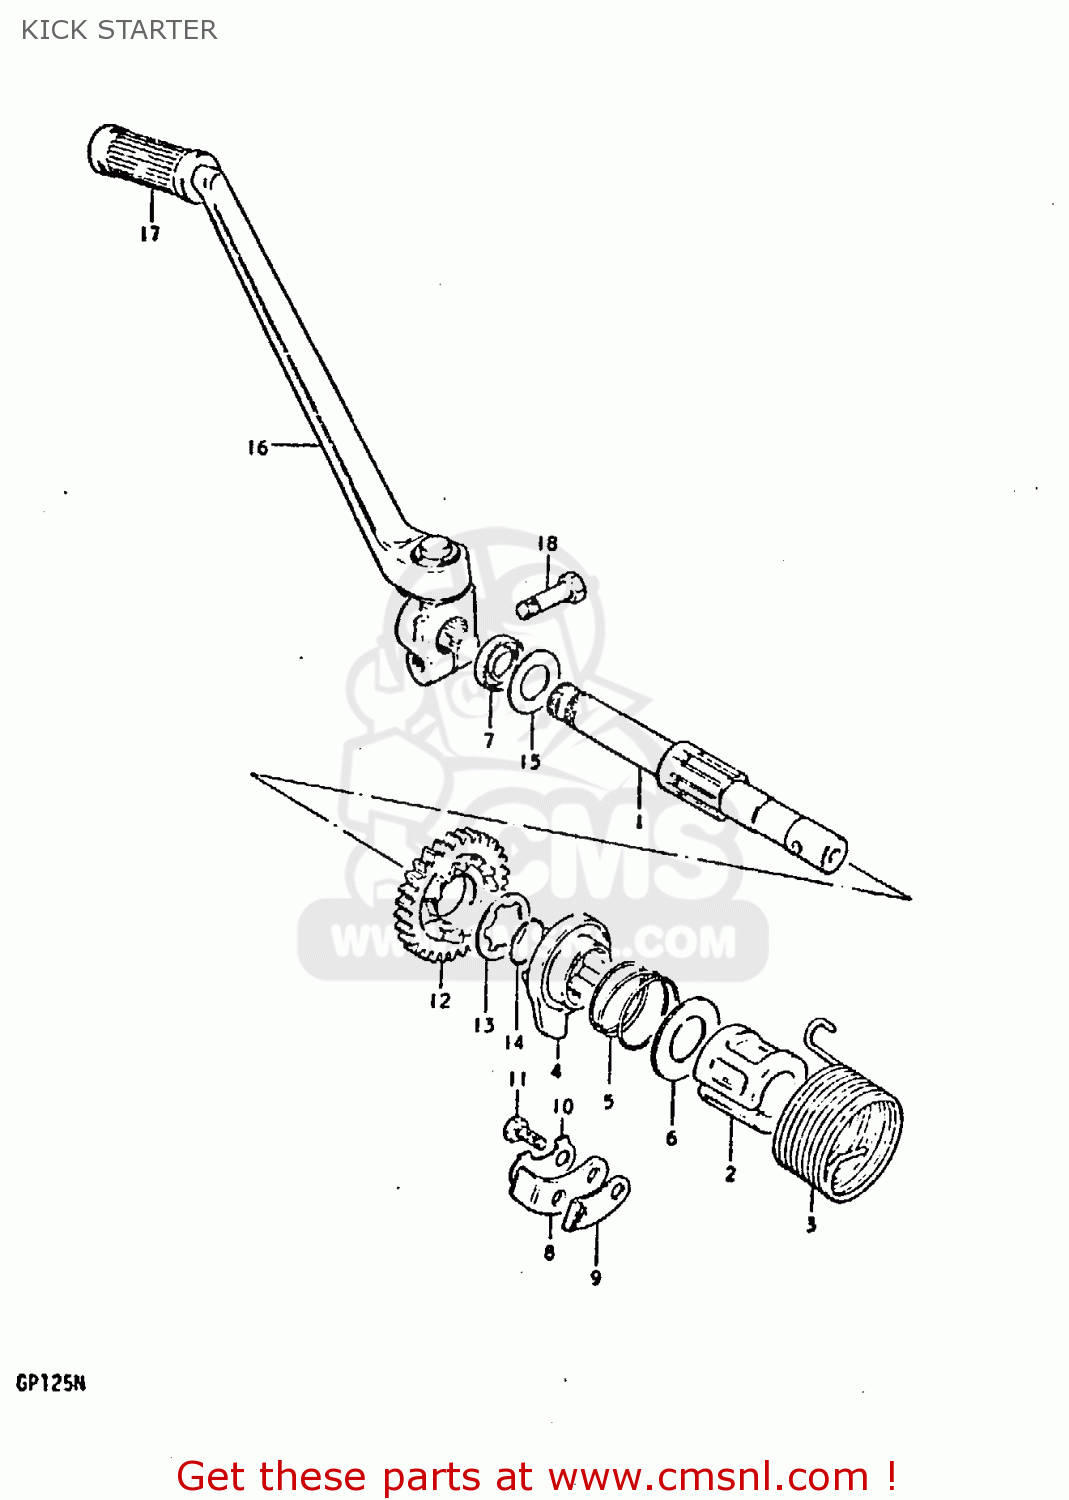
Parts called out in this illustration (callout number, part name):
1	SHAFT,KICK STARTER
2	GUIDE,KICK STARTER SFT SPRING
3	SPRING
4	STARTER,KICK
5	SPRING
6	WASHER
7	SEAL,OIL(16X30X8)
8	GUIDE,KICK STARTER
9	STOPPER,KICK STARTER
10	WASHER
11	BOLT, UPPER
12	GEAR,KICK STARTER DRIVE
13	WASHER,LOCK
14	CIRCLIP
15	WASHER(16X30X1)
16	LEVER ASSY,KICK STARTER
17	RUBBER,KICK STARTER PEDAL
18	BOLT
